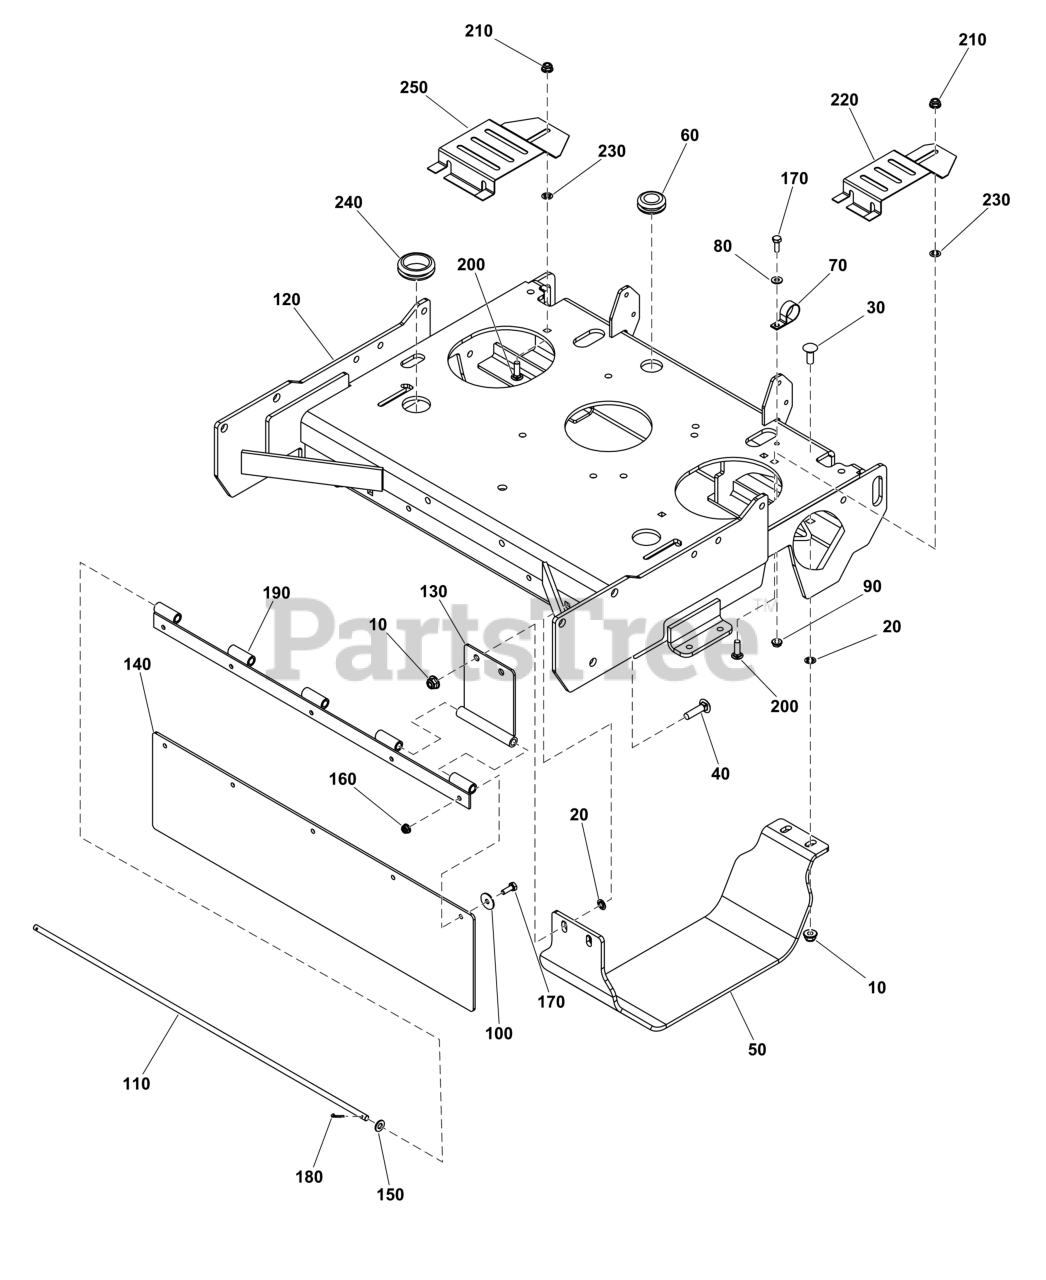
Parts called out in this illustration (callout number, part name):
10	NUT, 3/8-16 HEX NYLOCK
20	RETAINER, PUSHNUT,3/8
30	BOLT, RD HD, 3/8-16X1
40	BOLT, 3/8-16 X 1-1/2
60	GROMMET, 7/8"ID
80	WASHER
100	WASHER, 1/4 FENDER
120	DECK, ENGINE
150	WASHER
170	BOLT, 1/4-20 X 3/4" G
180	PIN, COTTER, 3/32X.75
200	BOLT, 5/16-18 X 1", C
210	NUT
220	PLATE, FAN GUARD, BV, LH - BLK
230	NUT, PUSH ON, 5/16
240	GROMMET, 1-1/2" ID FOR 1/4" METAL
250	PLATE, FAN GUARD - BLK
